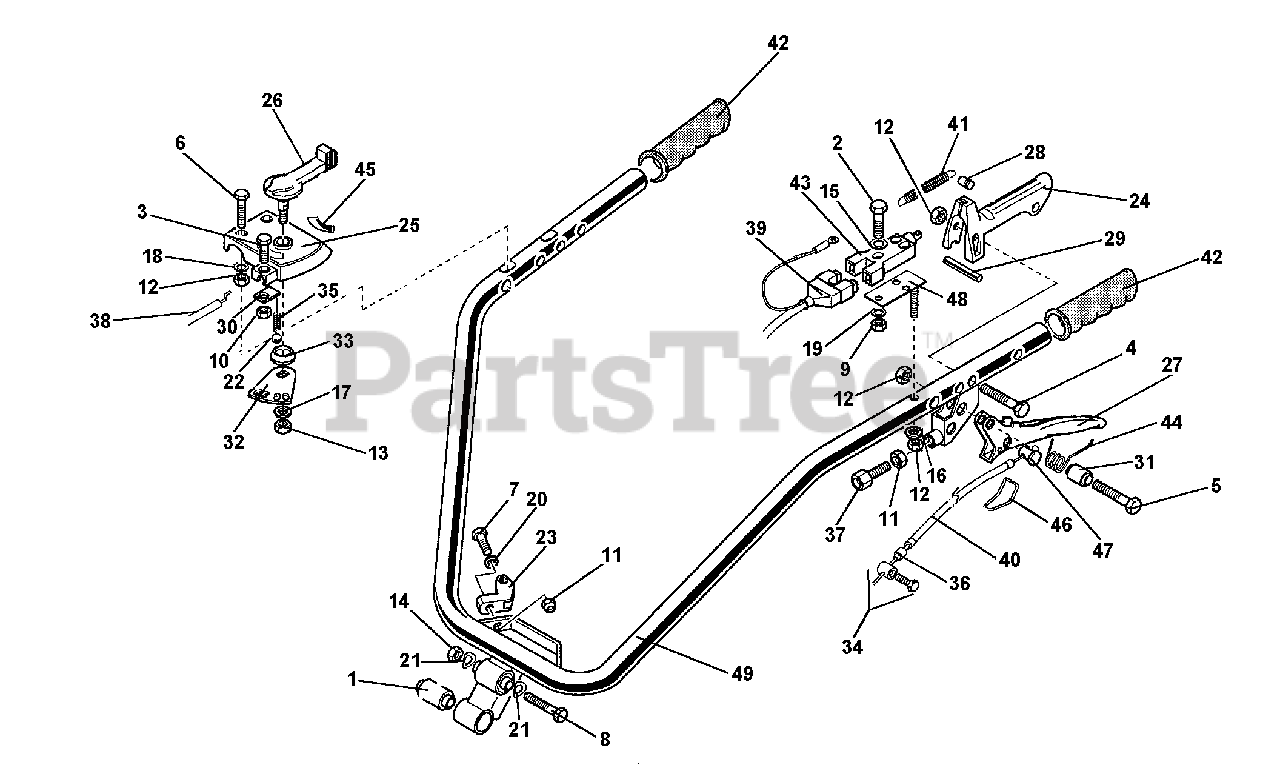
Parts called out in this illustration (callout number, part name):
1	SILENTBLOCK
2	SCREW TE M4X25
3	SCREW, M5X10
4	SCREW, TE M6X45
5	SCREW, M6X25
6	SCREW, M6X40
7	SCREW, M8X35
8	SCREW, M10X80
12	NUT, SELF LOCKING M6
15	FLAT WASHER, M4.3
16	WASHER, FLAT 6.4
17	WASHER, M8.4
18	LOCK WASHER, M6.4
19	LOCK WASHER, M4.3
20	WASHER, M8.4
21	WAVE WASHER, M10.4
23	SUPPORT, CONTROL ROD
24	MOTOR STOP LEVER
26	THROTTLE LEVER
27	CLUTCH LEVER
29	LEVER STOP FOR MOTOR STOP
31	LEVER SPACER
32	THROTTLE LEVER
34	CLAMP, CABLE
37	SCREW, ADJUSTING, M8
38	THROTTLE CABLE, B&S
39	SWITCH WIRING HARNESS
40	CLUTCH CABLE
43	STOP SWITCH
44	LEVER SPRING
45	THROTTLE DECAL
48	SWITCH PLATE
